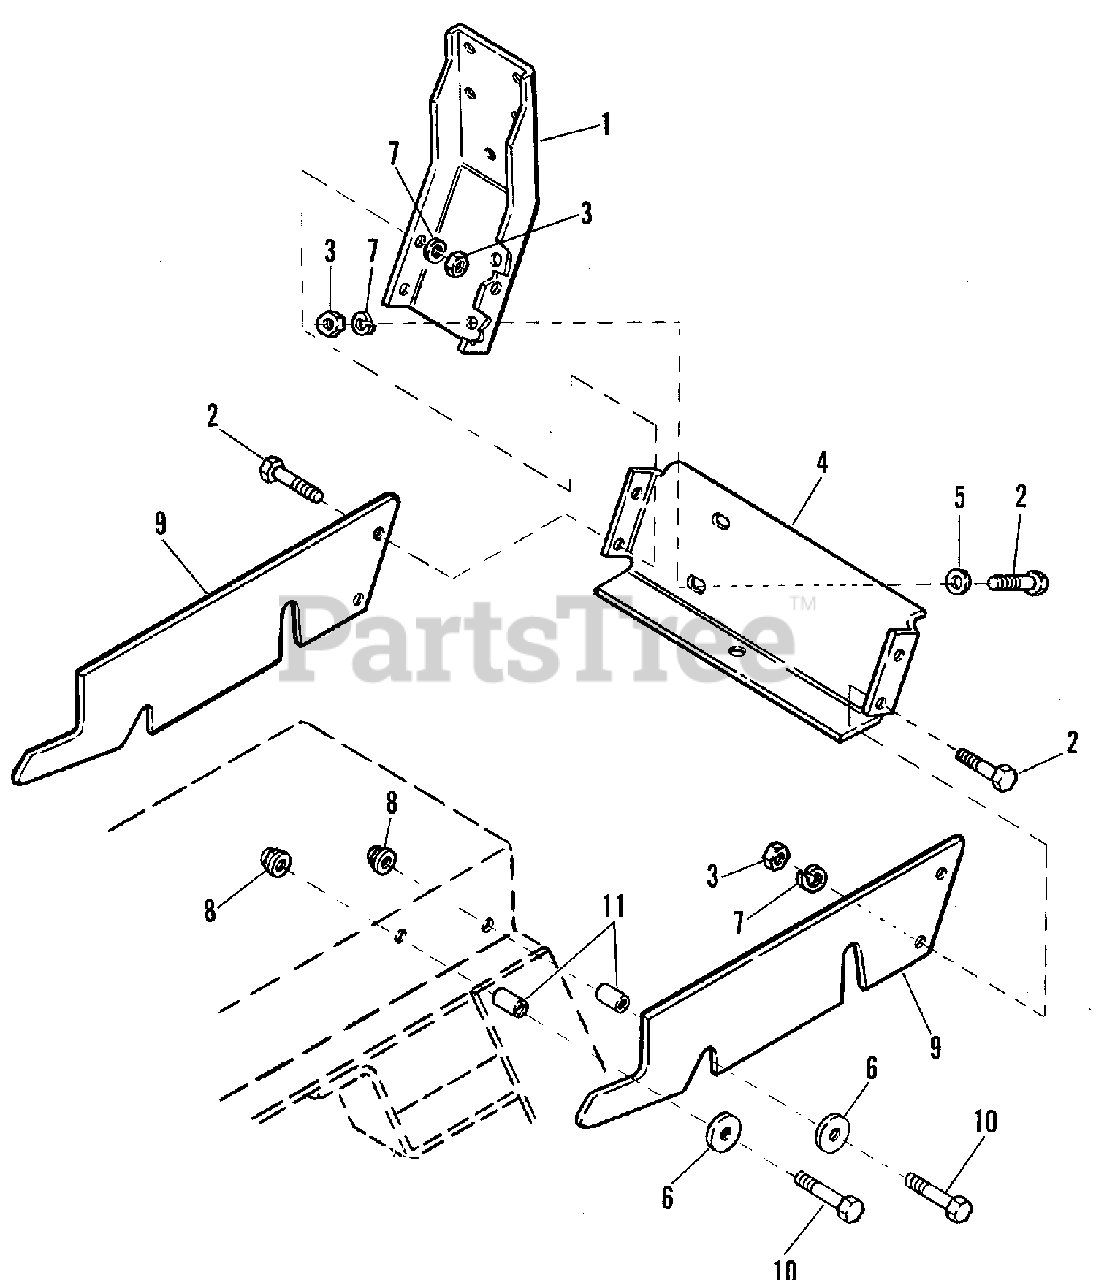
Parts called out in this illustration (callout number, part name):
1	SUPPORT, Upright
2	CAPSCREW, Hex Head, 3/8-16 x 1-1/4
3	NUT, Hex, 3/8-16
4	BRACKET, Lower Hitch
5	WASHER
6	WASHER
7	LOCKWASHER, 3/8
8	LOCKNUT, Hex, 1/2-13
9	SUPPORT, Side Hitch
10	CAPSCREW, Hex Head, 1/2-13 x 2-1/2
